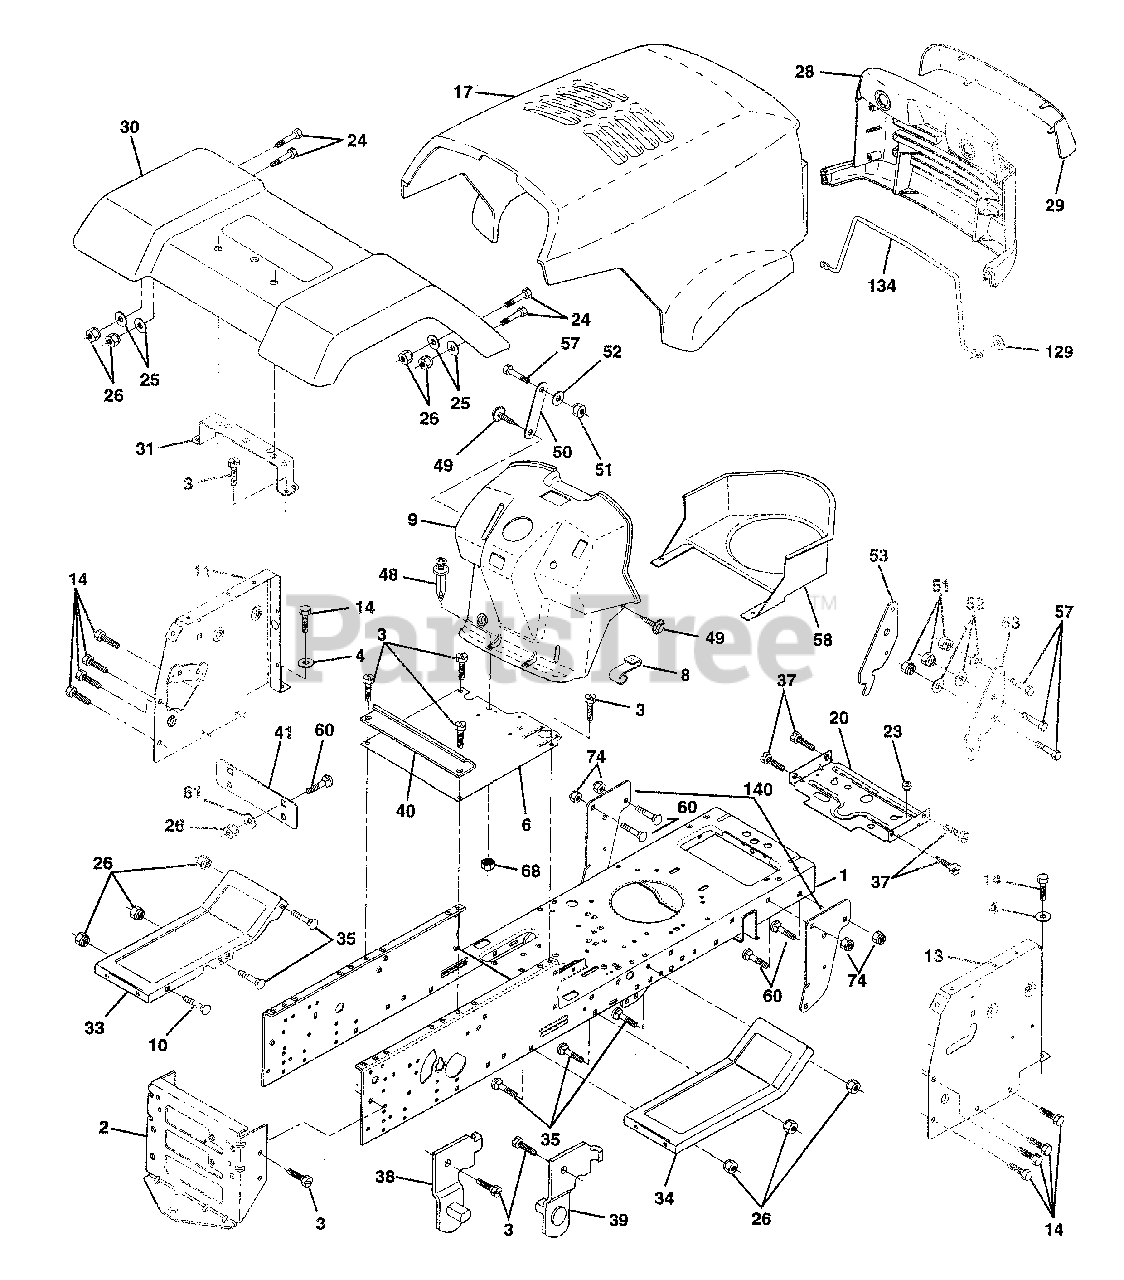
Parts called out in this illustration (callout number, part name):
1	Chassis Weldment 11 ga
2	Drawbar, Stretch
3	Screw Thdrol 3/8-16x3/4 Ty-tt
4	Washer 13/32 x 3/4 x 16 Ga.
6	Saddle LT Fender Shift
8	Clip Insulator .406 Mtg Hole
9	Dash Private Label
10	Bolt Carriage 3/8-16 x 1
11	Panel Pnt Dash Lh
12	Clip Tinnerman P/L
13	Panel Dash Rh
14	Screw Thdrol 3/8-16x1/2 Ty-tt
17	Hood Private Label LT Husq
20	Plate Pnt Mtg Btry/FL
24	Bolt Fin Hex 3/8-16unc X 1 Gr. 5
25	Washer 13/32 X 13/16 X 12 Ga
26	Nut Lock Hex W/Ins 3/8-16 UNC
28	Grille Private Label/LT
29	Lens Grille Private Label
30	Fender Pnt
31	Bracket Pnt Support Fender
33	Footrest Pnt Lh
34	Footrest Pnt Rh
35	Bolt Rdhd Sht Sqnk 3/8-16 X3/4
37	Screw Thdrol 5/16-18 X 1/2
38	Bracket, Asm. Pivot, L.H., Mower Rear
39	Bracket, Asm. Pivot, R.H., Mower Rear
40	Spacer Fender Lt
41	Plate Extension Fender Lt
48	Rivet Push Plate D Plastic Blk
49	Screw Hexwsh. Thdrol 1/4-20 x 3/4
51	Nut Lock Hex W/Ins 1/4-20
52	Washer 9/32 x 7/8 x 16 Ga.
53	Bracket Pnt. Pick Off LT/PL Husq
57	Screw Hex 1/4-20 x 3/4
58	Air Duct P/L
60	Bolt Carriage 3/8-16 x 3/4
61	Washer 17/32 x 7/8 x 16 Ga.
68	Nut Keps Hex 1/4-20 Unc
74	Nut Crownlock 3/8-16 Unc
129	Washer 9/32 x 5/8 x 16 Ga.
134	Rod Support Hood LT/PL Husq.
140	Bracket Chassis Front
